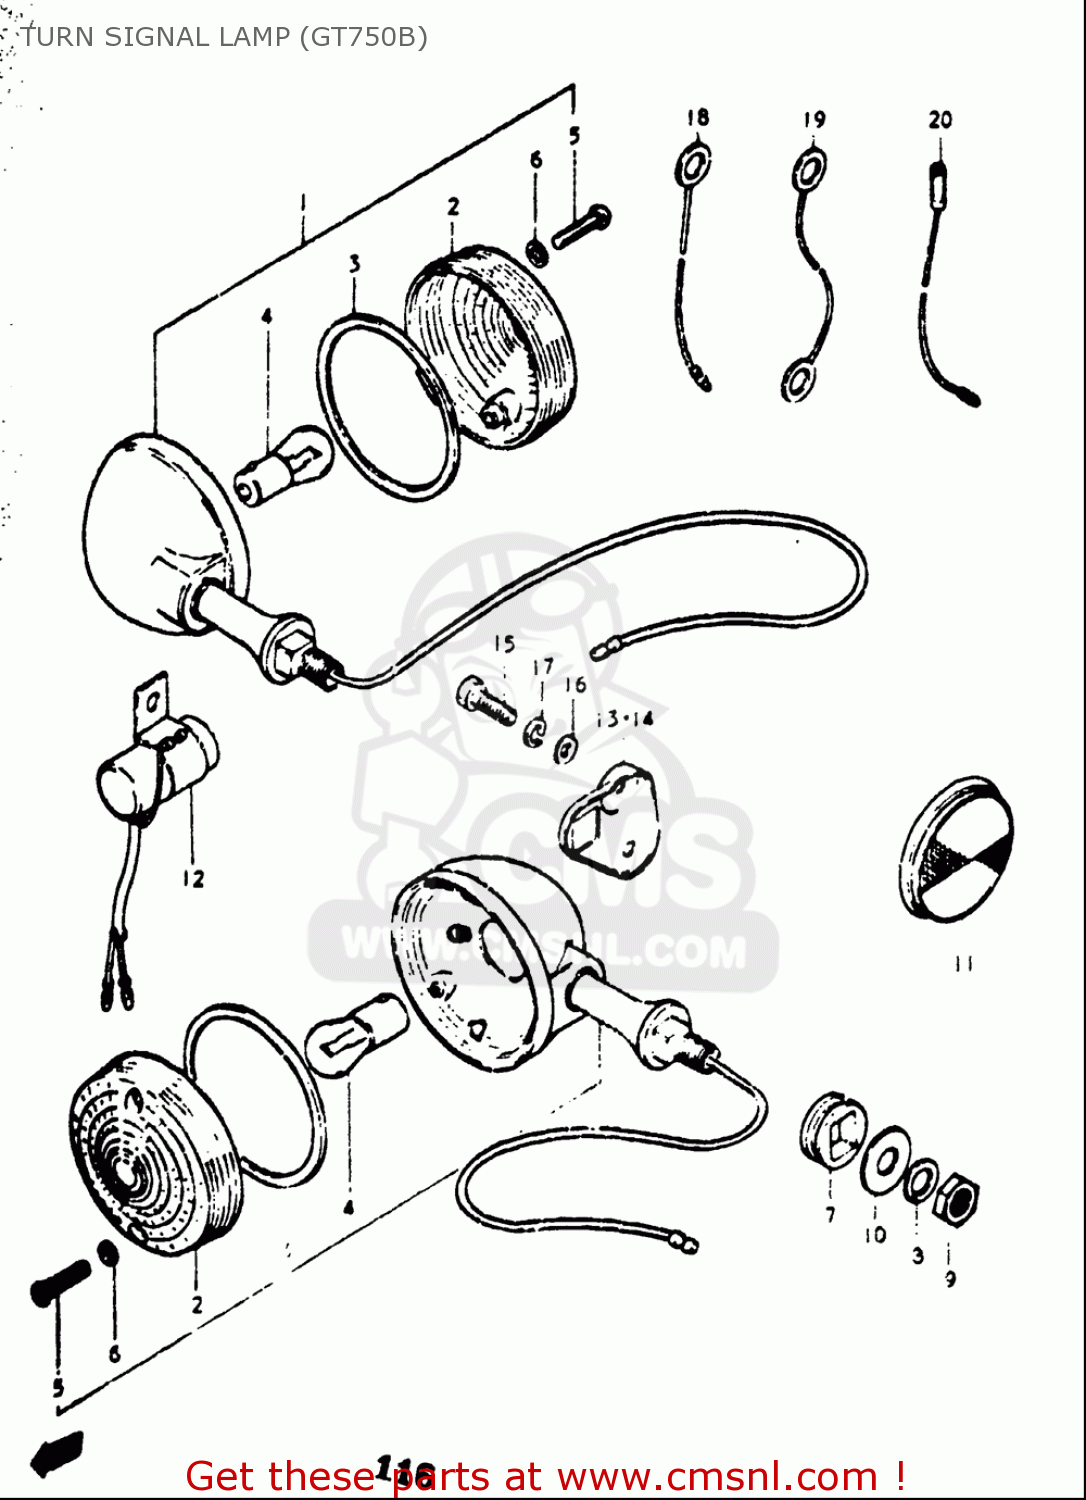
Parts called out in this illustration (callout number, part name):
1	LAMP ASSY,FR TURN SIGNAL
2	LENS
3	GASKET (NAS)
4	BULB(12V23W,STANLEY,A4577A)
5	SCREW(4X30)
6	GASKET (NAS)
7	CUSHION
8	WASHER,LOCK
9	NUT
10	WASHER(10.5X30X2.3)
11	REFLEX REFLECTOR,FR
12	RELAY,TURN SIGNAL
13	BRACKET, REAR TURN SIGNAL RH
14	BRACKET, REAR TURN SIGNAL LH
15	BOLT
16	WASHER
17	WASHER,LOCK
18	LEAD WIRE,EARTH
